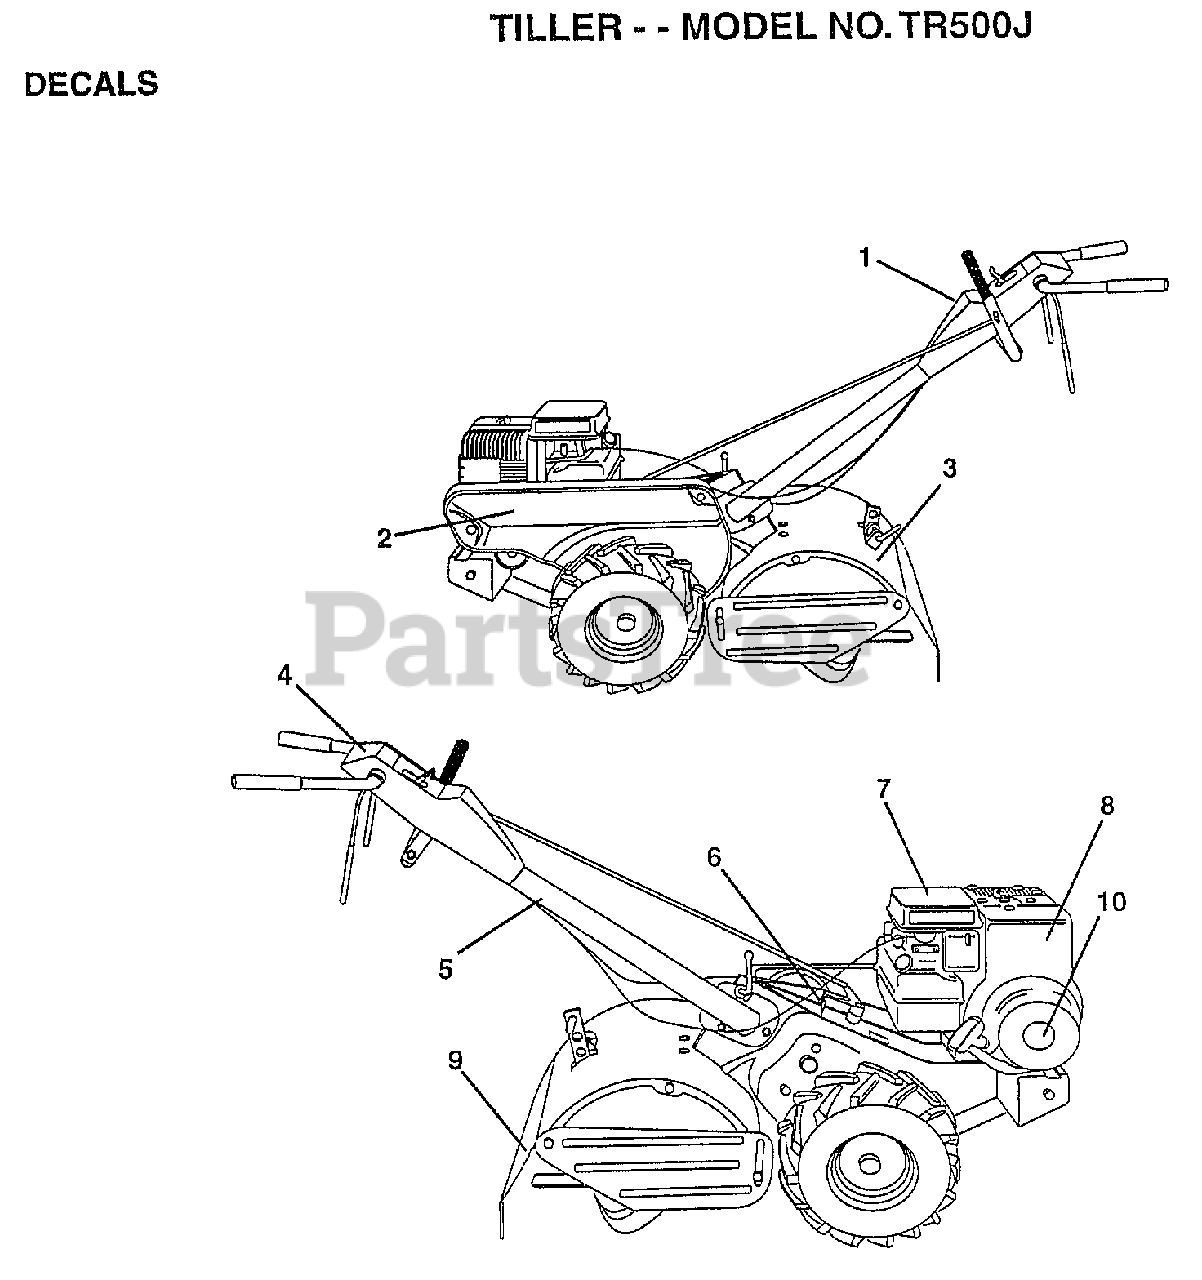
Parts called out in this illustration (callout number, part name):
1	DECAL.PNL.CONTROL
3	DECAL.SHLD.TINE
4	DECAL.INSTRUCTION
5	DECAL TI
6	DECAL CRT
8	DECAL, BRIGGS & STRATTON
9	DECAL TI
10	DECAL, 5 HP
